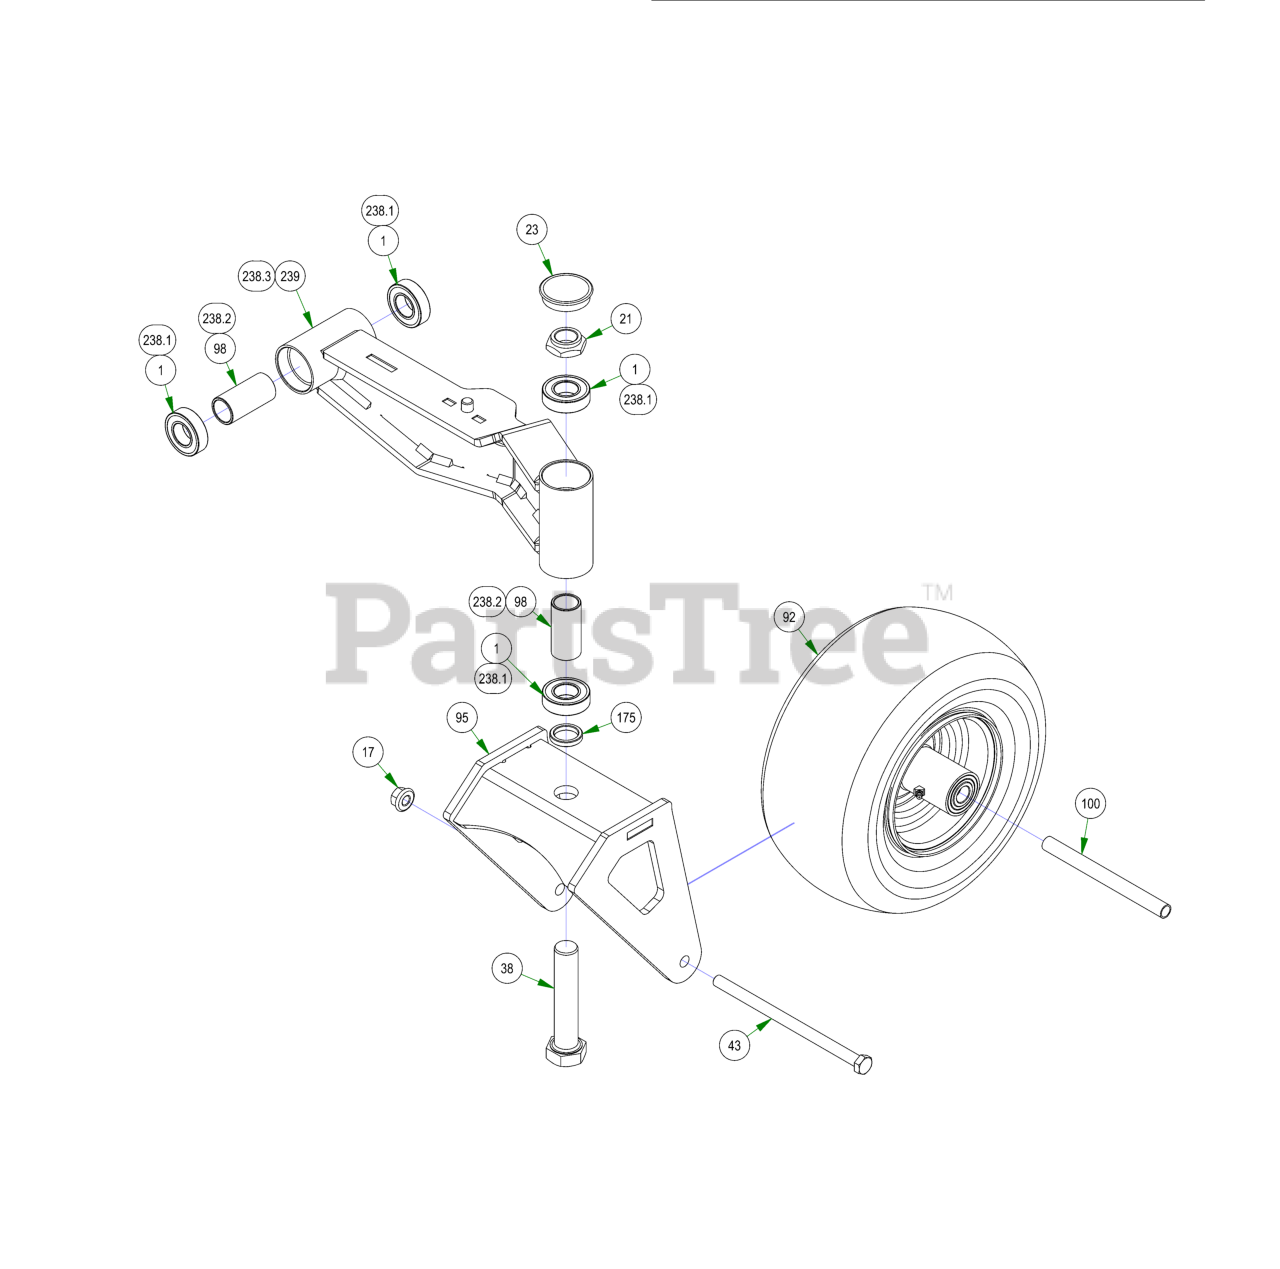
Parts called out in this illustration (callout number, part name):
1	1641 BEARING W/2 CONTACT RUBBER SEALS
17	1/2-13 NYLON INSERT FLANGE LOCKNUT ZINC
21	1"-14 NYLON INSERT JAM LOCKNUT ZINC
23	2017 Bearing Cover
38	1"-14 X 5 HEX CAP SCREW (GR.8) ZINC YELLOW
43	1/2-13 X 8-1/2 HEX CAP SCREW (GR.5) ZINC
92	13x6.50-6 Black No Flat Assembly
95	2019 Stand-on Front Fork Weldment
98	2016 Front Bearing Spacer
100	Front Wheel Spanner
175	Spacer, 1x1.375x.25
238	2021 Maverick LH Front Suspension Arm Assy (48", 54" & 60")
238.1	1641 BEARING W/2 CONTACT RUBBER SEALS
238.2	2016 Front Bearing Spacer
238.3	2021 Maverick I-Beam Front Arm LH Weldment - Painted
239	2022 42" Maverick I-Beam Front Arm - LH - Painted
